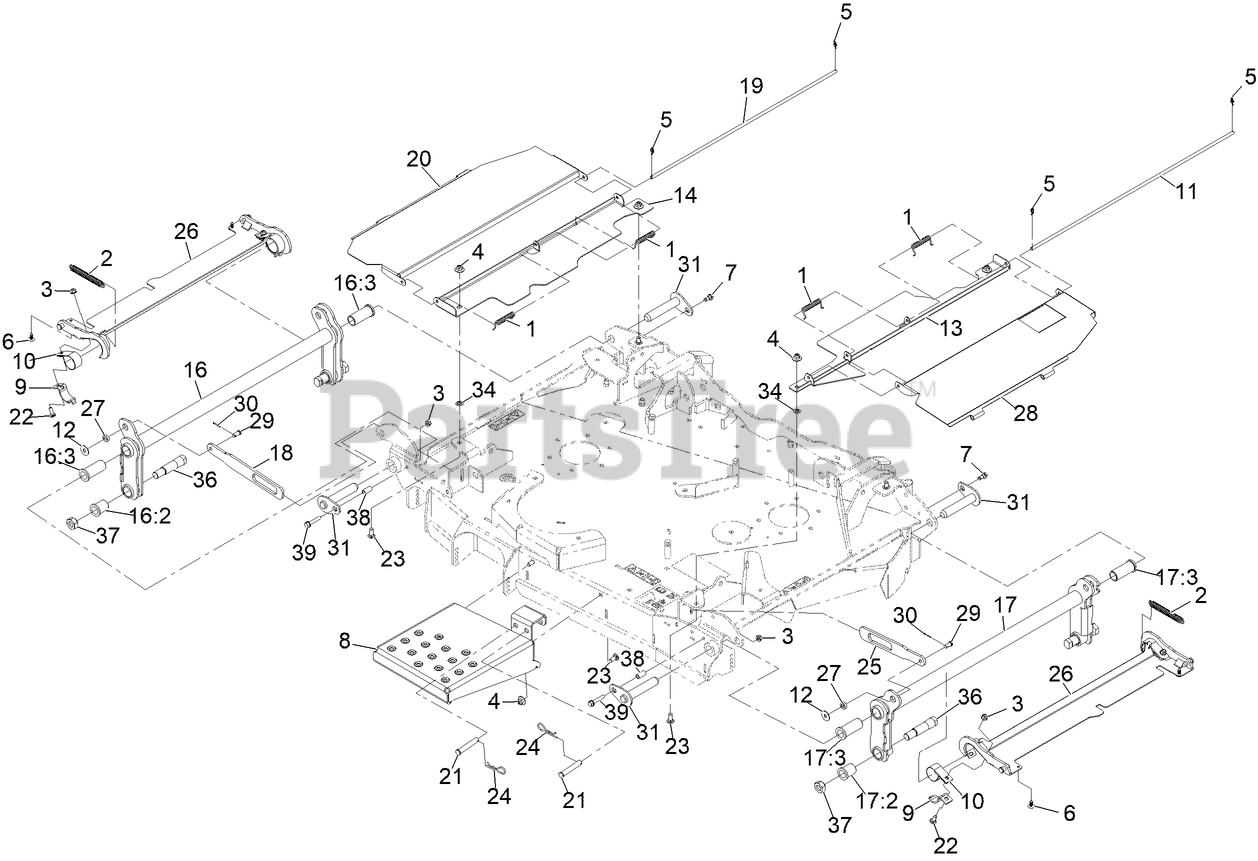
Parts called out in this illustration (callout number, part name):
1	SPRING-TORSION
3	NUT-HF, NI
4	Nut-Nyloc 3/8-16 Flg
5	PIN-COTTER, LOCKING
6	PLUG-PLASTIC
7	SCREW-SHOULDER
8	PLATE-DECK STEP
9	PLATE-RETAINER, BEARING
10	BEARING-STRAP, NYLON
11	COVER-ROD, PIVOT
13	SHIELD-LH CENTER [RED]
14	SHIELD-CENTER, RH
16	ASM-RH FOLD ARM
16:2	BUSHING-FLANGED
16:3	BUSHING-FLANGED
17	ASM-LH FOLD ARM
17:2	BUSHING-FLANGED
17:3	BUSHING-FLANGED
18	STRAP-RH FLAG
19	ROD-CENTER COVER
20	PLATE-HINGED COVER
21	PIN-CLEVIS
22	SCREW-CARR
23	BOLT-CARR
24	PIN-HAIR
25	STRAP-LH FLAG
26	ASM-WING COVER, [RED]
27	BUSHING
28	COVER-HINGED, LH [BLACK]
29	PIN-CLEVIS
30	Pin-Cotter
31	ASM-DECK PIN
34	NUT-PUSH
36	BOLT-PIVOT PIN
37	NUT-LUG
38	Tube-Standoff
39	Screw-HWH
